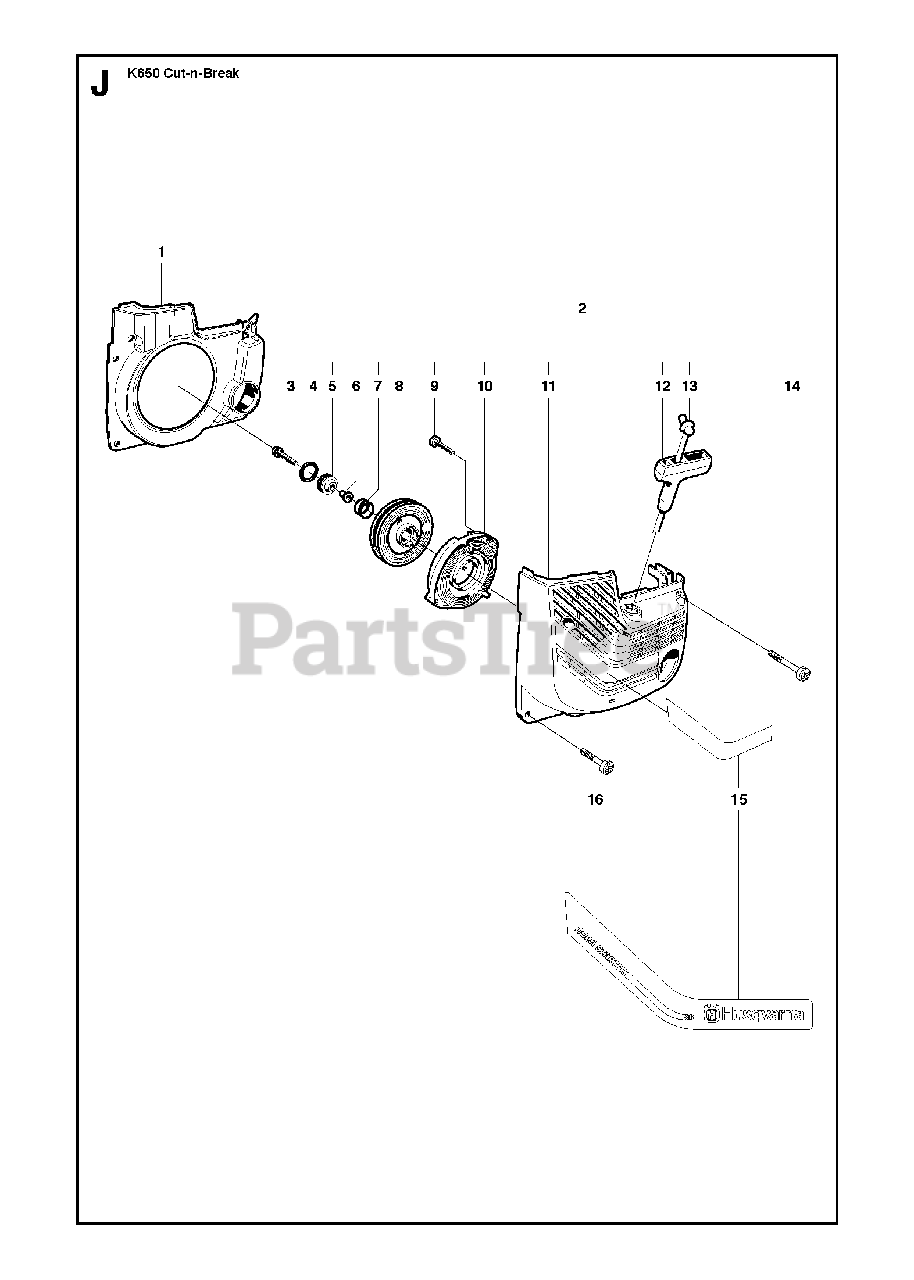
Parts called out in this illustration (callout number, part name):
3	SCREW IHSCFT
5	GROMMET
6	SPACING SLEEVE
7	COMPRESSION SPRING
8	STARTER PULLEY
9	SCREW CCRPANT
10	RECOIL SPRING
12	STARTER HANDLE
14	SCREW CCRPANMO
16	SCREW CCRPANMO
